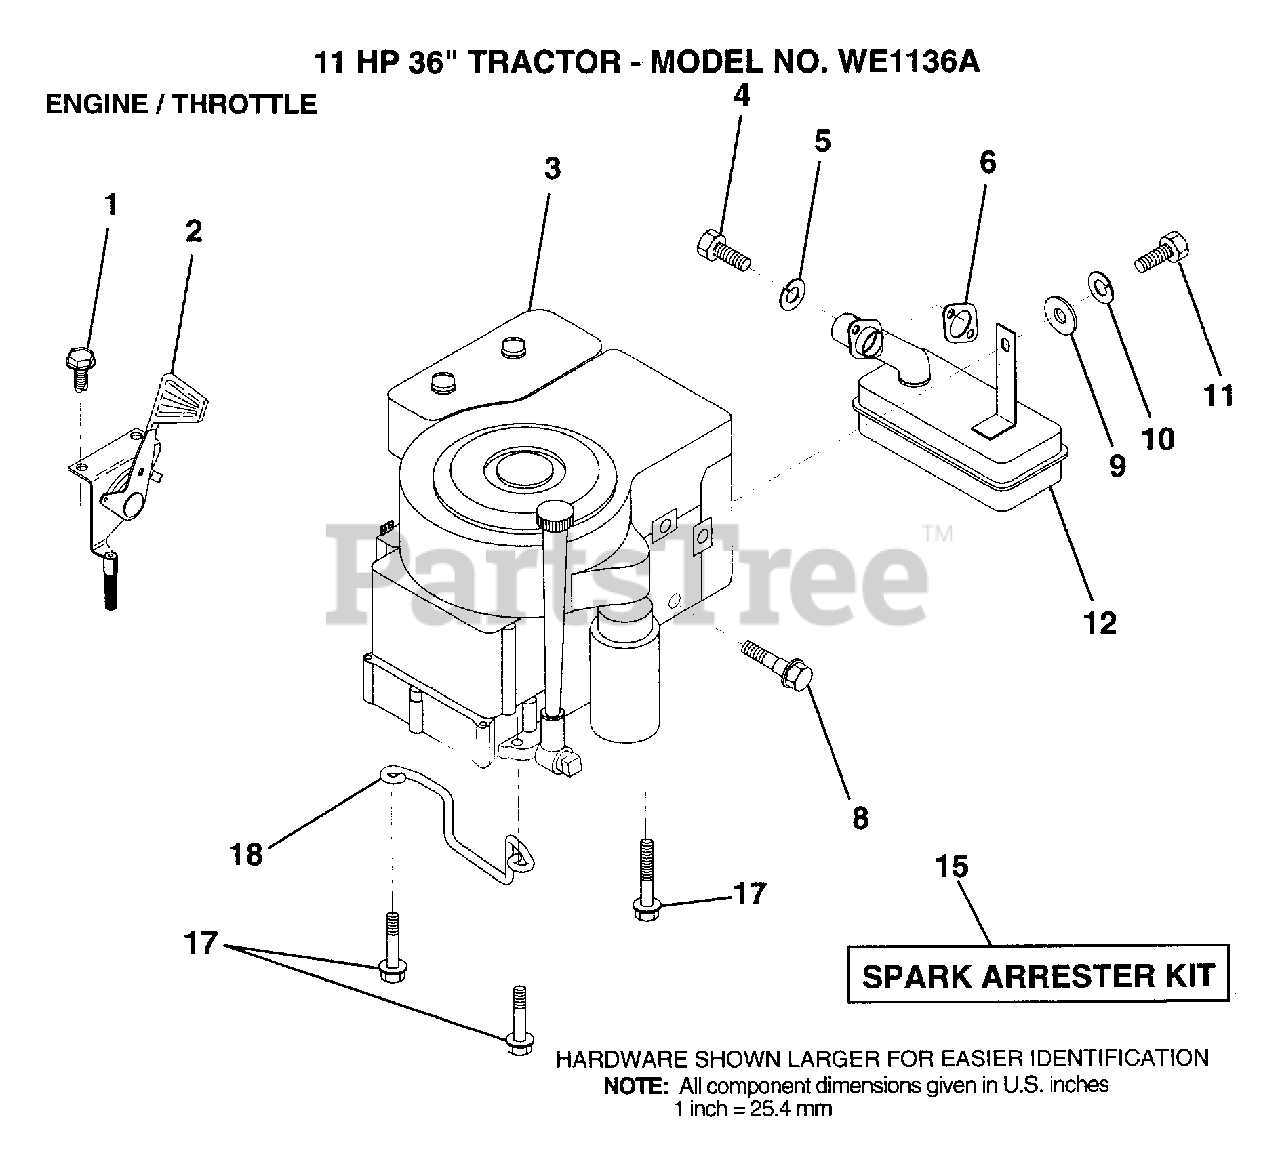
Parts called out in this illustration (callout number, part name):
1	SCREW
2	THROTTLE CONTROL
3	ENGINE B&S 11HP
4	SCREW
5	LOCKWASHER
8	BOLT T
10	LOCKWASHER
11	BOLT
12	MUFFLER
17	SCREW LT
18	"KEEPER,DR BELT GR"
